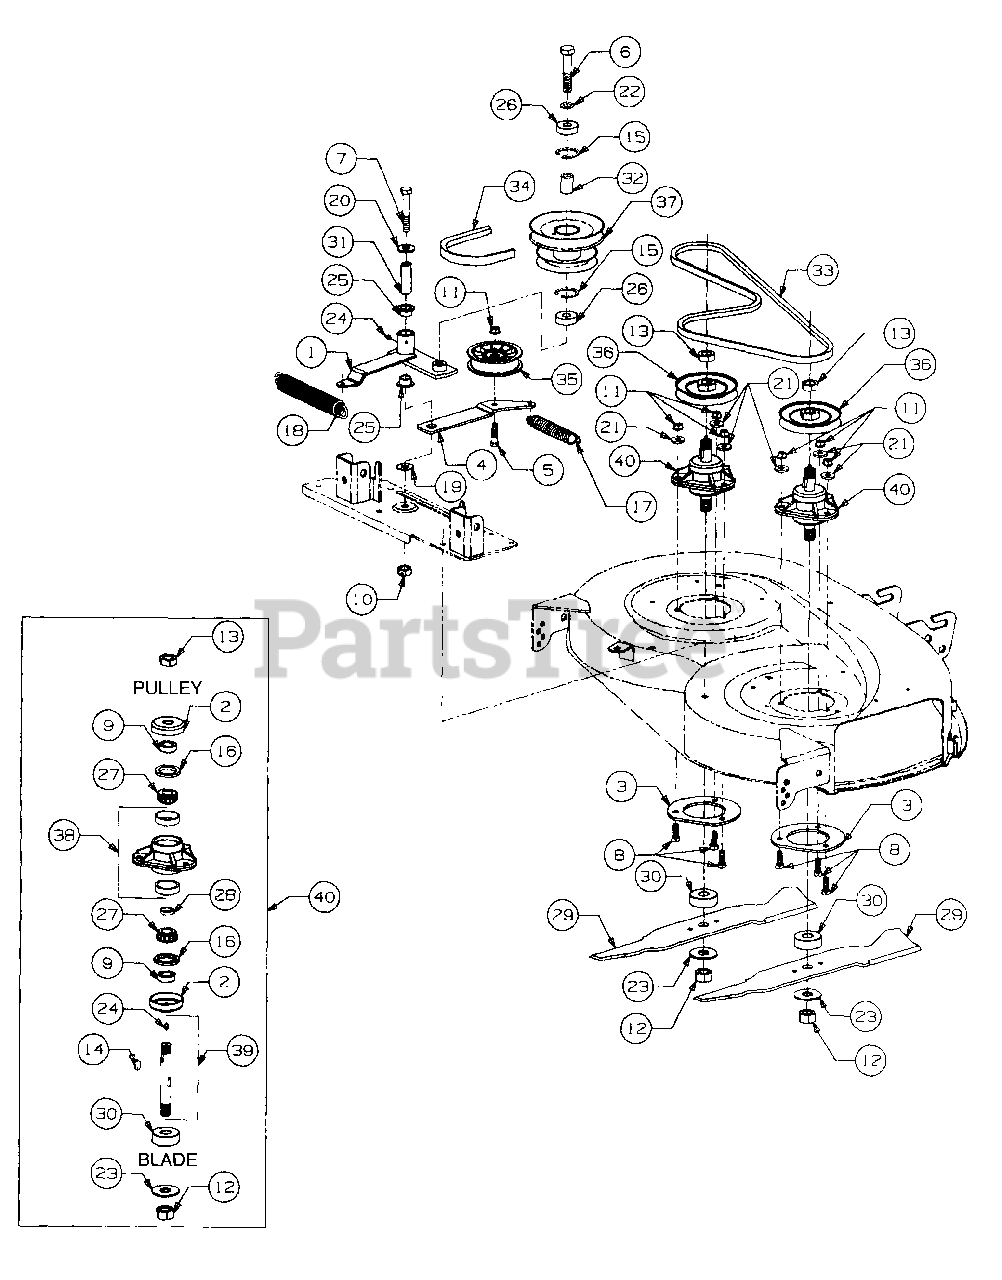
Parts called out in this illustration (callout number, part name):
2	Cup, Spindle Hdn
3	Plate, Spindle Mounting
5	Screw, Hex Cap 3/8-16 x 1.5 GR5
6	Screw, Hex Cap 5/8-18 x 3.0 GR5
7	Screw, Hex Gap 1/2-20 x 3.0 GR8
8	Screw, Hex Cap 3/8-16 x 1.25 GR5
9	Spacer, .755 x 1.25 x .44
10	Nut, Hex Center Lock, 1/2-20
11	Nut, Hex Flange Lock, 3/8-16
12	Nut, Hex, 3/4-16 GR8
13	Nut, Hex Jam, 3/4-16 GR5
14	Key, #91 Woodruff, 1/4 x 3/4 Hdn
15	Snap Ring, Internal
16	Seal, Oil, 1.25 x 1.874 x .25
17	Spring, Extension, .88 x 6.12
18	Spring, Extension, 1.25 x 8.15
19	Washer, Flat, .531 x 1.25 x .036
20	Washer, Flat, .531 x 1.25 x .100
21	Washer, Flat, .385 x 1.0 x .135
22	Washer, Flat, .63 x 1.0 x .063 Hdn
23	Washer, Flat, .781 x 2.0 x .105
24	Fitting, 3/16 Drive Lube
25	Bearing, Flange, 3/4 ID x 53 Lg
26	Bearing, Ball, .62 ID x 1.57 OD
27	Cone, Bearing
28	Spacer, Bearing
29	Blade, Low Lift, 19.38 Lg
30	Spacer
31	Spacer, Idler Brkt .50 ID x .75 OD x 2.25 Lg
32	Spacer, Pulley .635 ID x .88 OD x 1.25 Lg
33	Belt, Spindle, A-Section x .59 Lg
34	Belt, PTO, B-Section x 112.4 Lg
35	Pulley, Flat Idler, 3.5 OD
36	V-Pulley, 4.62 OD
37	Pulley, Double
38	Housing w/Cups, Spindle
39	Kit, Shaft w/Seal
40	Spindle Assembly, Blade
